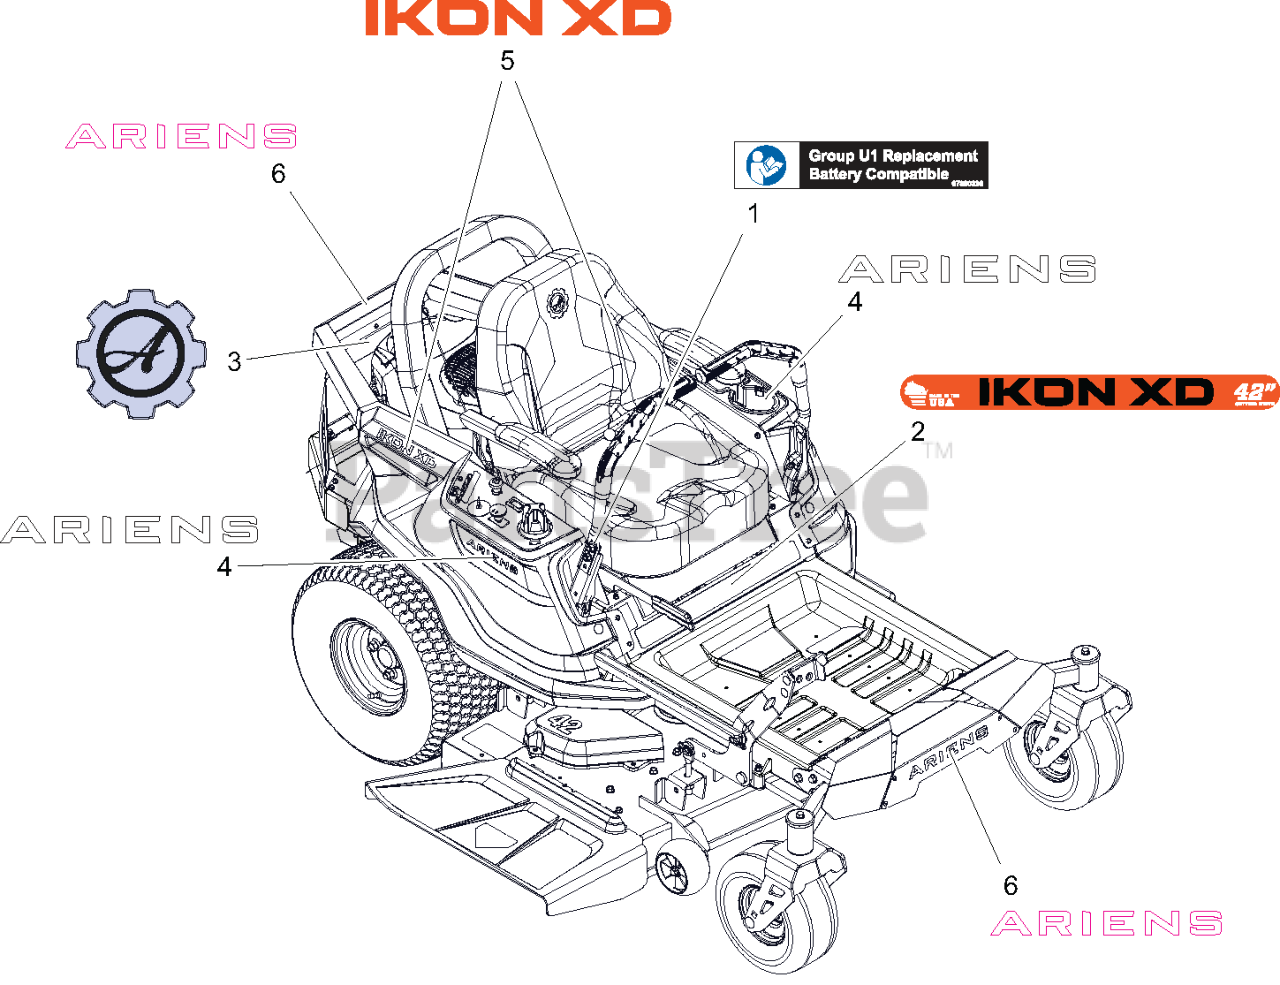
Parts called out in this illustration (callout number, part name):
1	DECAL, U1 BATTERY REPLACEMENT
2	DECAL, IKON XD - 42
3	DECAL, ARIENS - GEAR BADGE
4	DECAL, ARIENS (6.50")
5	DECAL, FENDER - IKON XD
6	DECAL - ARIENS 9.625"
